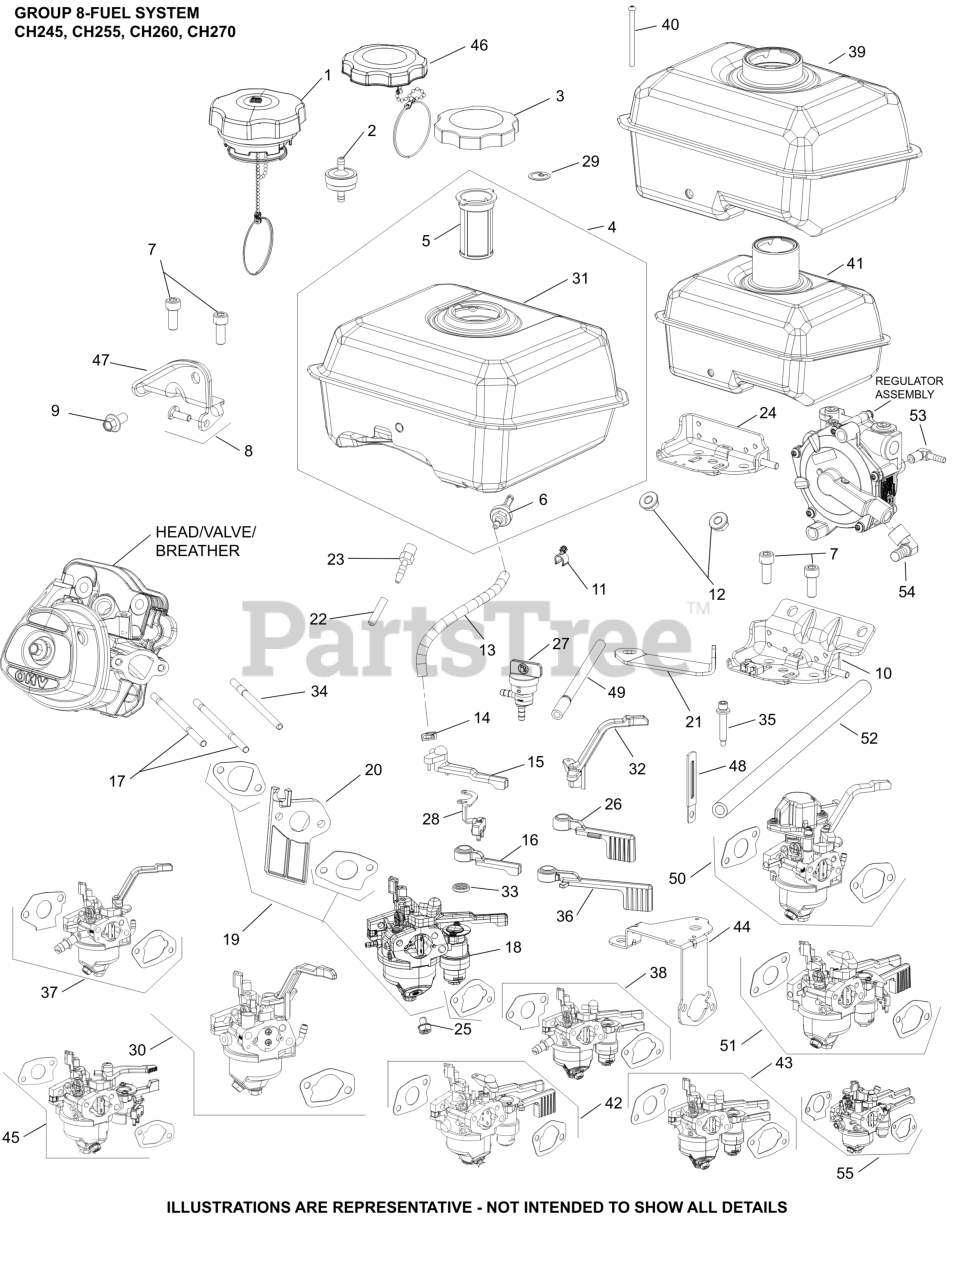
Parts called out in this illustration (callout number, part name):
1	CAP, FUEL ASSEMBLY
4	KIT, FUEL TANK ASSEMBLY
5	FILTER, FUEL TANK
6	FITTING, FUEL ASSY
11	CLIP, FUEL HOSE
13	LINE, FUEL (10"-CUT TO LENGTH)
14	CLAMP, FUEL LINE
17	STUD, CARBURETOR
18	KIT, CARBURETOR
19	KIT, INTAKE GASKET
20	INSULATOR, CARBURETOR
NI	KIT, HIGH ALT (4000-8000 FT)
NI	KIT, HIGH ALT (8,000+ FT)
NI	KIT, CARBURETOR REPAIR (RUIXING)
